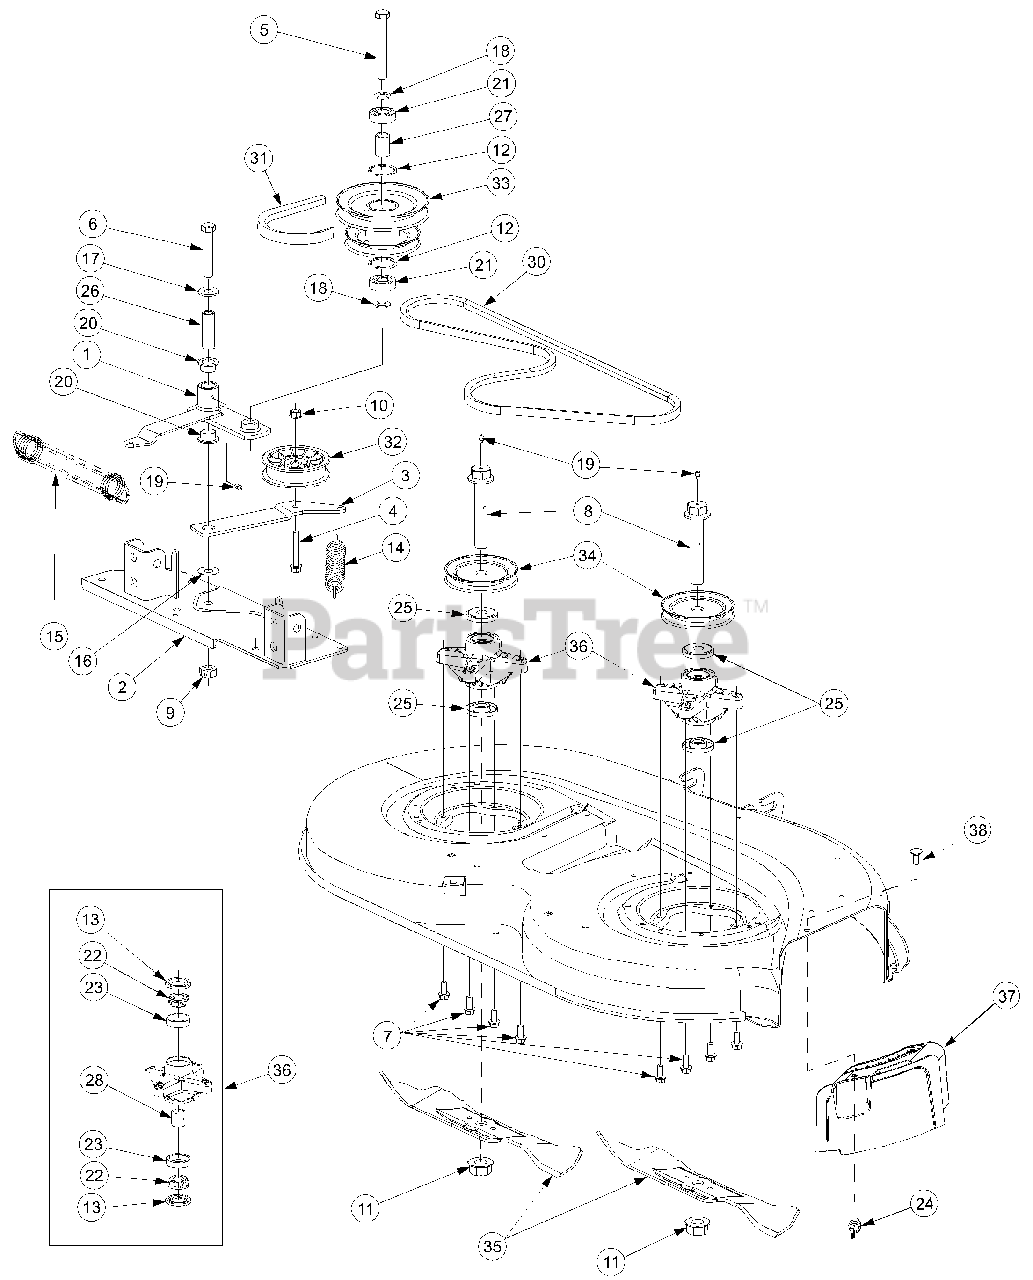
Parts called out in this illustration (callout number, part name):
1	Pivot Arm, Double Pulley
4	Screw, Hex Cap, 3/8-16 x 1.5 GR5
5	Screw, Hex Cap, 5/8-18 x 3.0 GR5
6	Screw, Hex Cap, 1/2-20 x 3.0 GR8
7	Screw, Hex Wsh Hd Tap, 5/16-18 x .75
8	Bolt, Spindle, 3/4-16 x 4.25
9	Nut, Hex Center Lock, 1/2-20
10	Nut, Hex Flange Lock, 3/8-16
11	Nut, Hex Flange, 3/4-16
12	Snap Ring, Internal
13	Seal, Oil, 1.25 x 1.874 x .25
14	Spring, Extension, .88 x 6.12
15	Spring, Extension, 1.25 x 8.15
16	Washer, Flat, .531 x 1.25 x .036
17	Washer, Flat, .531 x 1.25 x .100
18	Washer, Flat, .65 x 1.25 x .075 Hdn.
19	Fitting, 3/16 Drive Lube
20	Bearing, Flange, 3/4 ID x .53 Lg
21	Bearing, .625 ID x 1.574 OD x 470
22	Cone, Bearing
23	Cup, Bearing
24	Nut, Wing, 1/4-20
25	Spacer, Deck Spindle
26	Spacer, Idlr Brkt .50 ID x .75 OD x 2.25
27	Spacer, Pulley .635 ID x .88 OD x 1.25
28	Spacer, Bearing, .780 x .963 x .777
30	Belt, Spindle, A-Section x 61 Lg
31	Belt, PTO, B-Section x 111.2 Lg
32	Pulley, Flat Idler, 3.5 OD
33	Pulley, Double
34	V-Pulley, 4.0 Dia
35	Blade, 3 In One, 21.20 Lg
36	Spindle, Blade
37	Plug, Mulch
38	Screw, Carriage, 1/4-20 x .62
